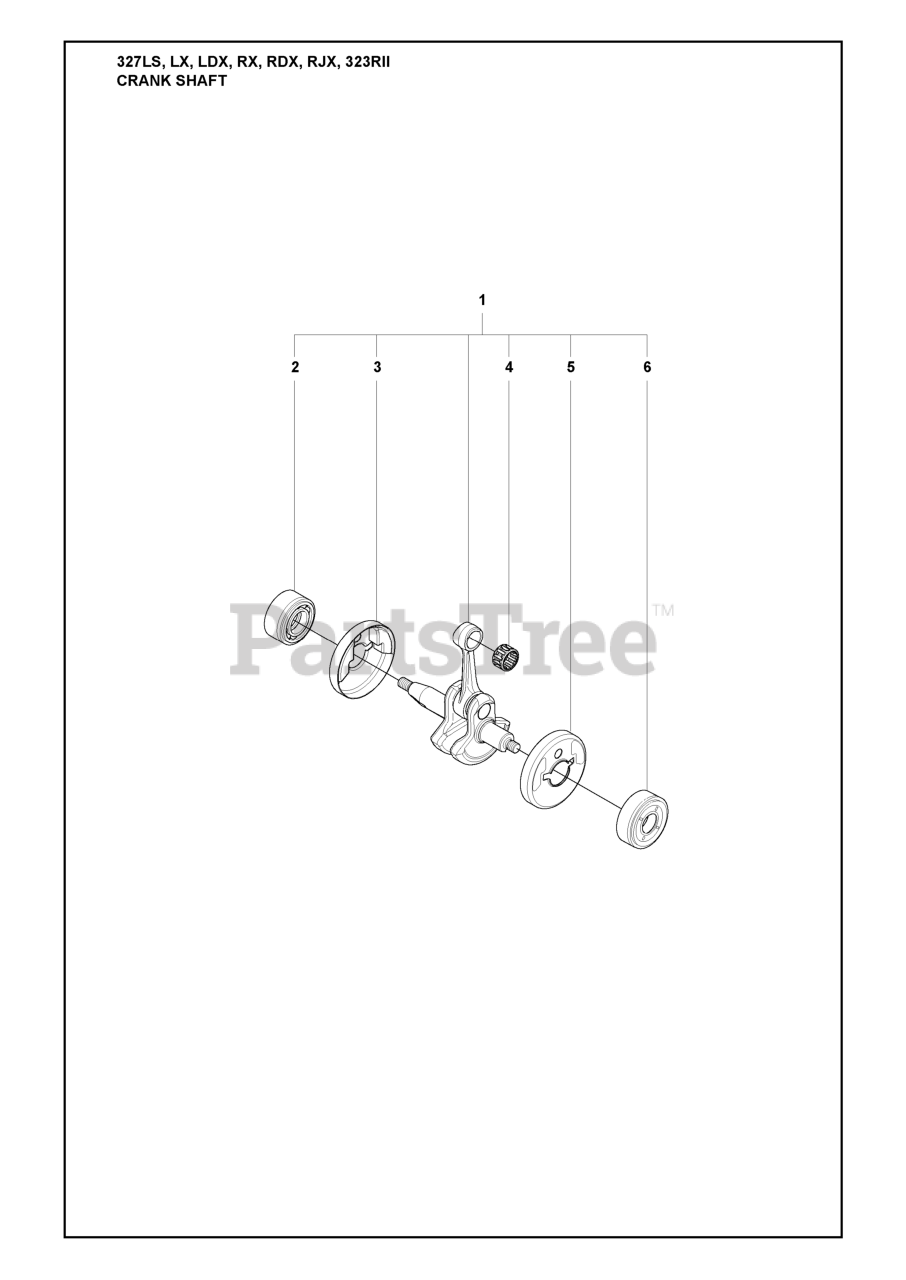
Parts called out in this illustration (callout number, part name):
1	CRANKSHAFT
2	BEARING CAP
6	BEARING CAP
